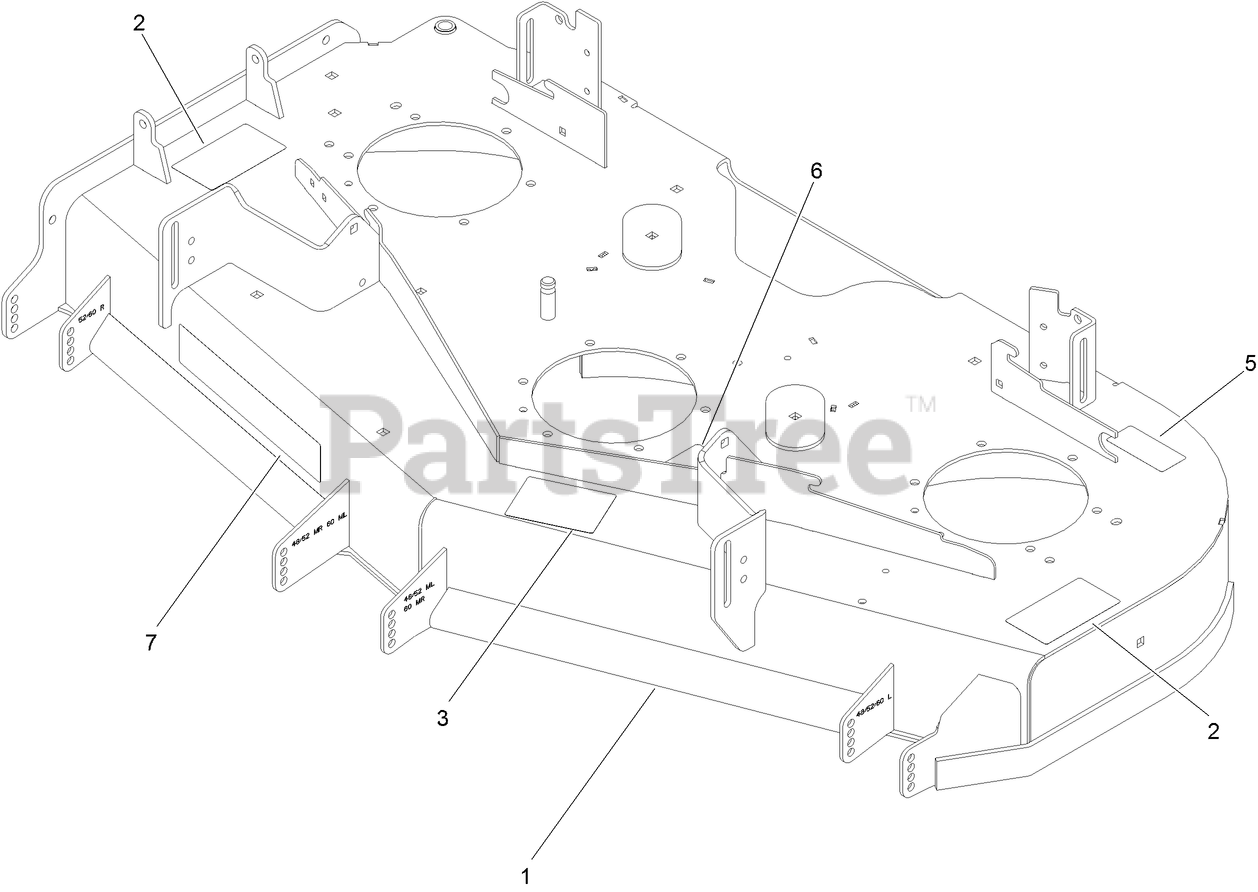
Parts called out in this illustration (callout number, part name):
2	DECAL-DANGER
3	DECAL-SCALP, ANTI
5	DECAL-BOLT TORQUE
6	DECAL-ROUTING, BELT
